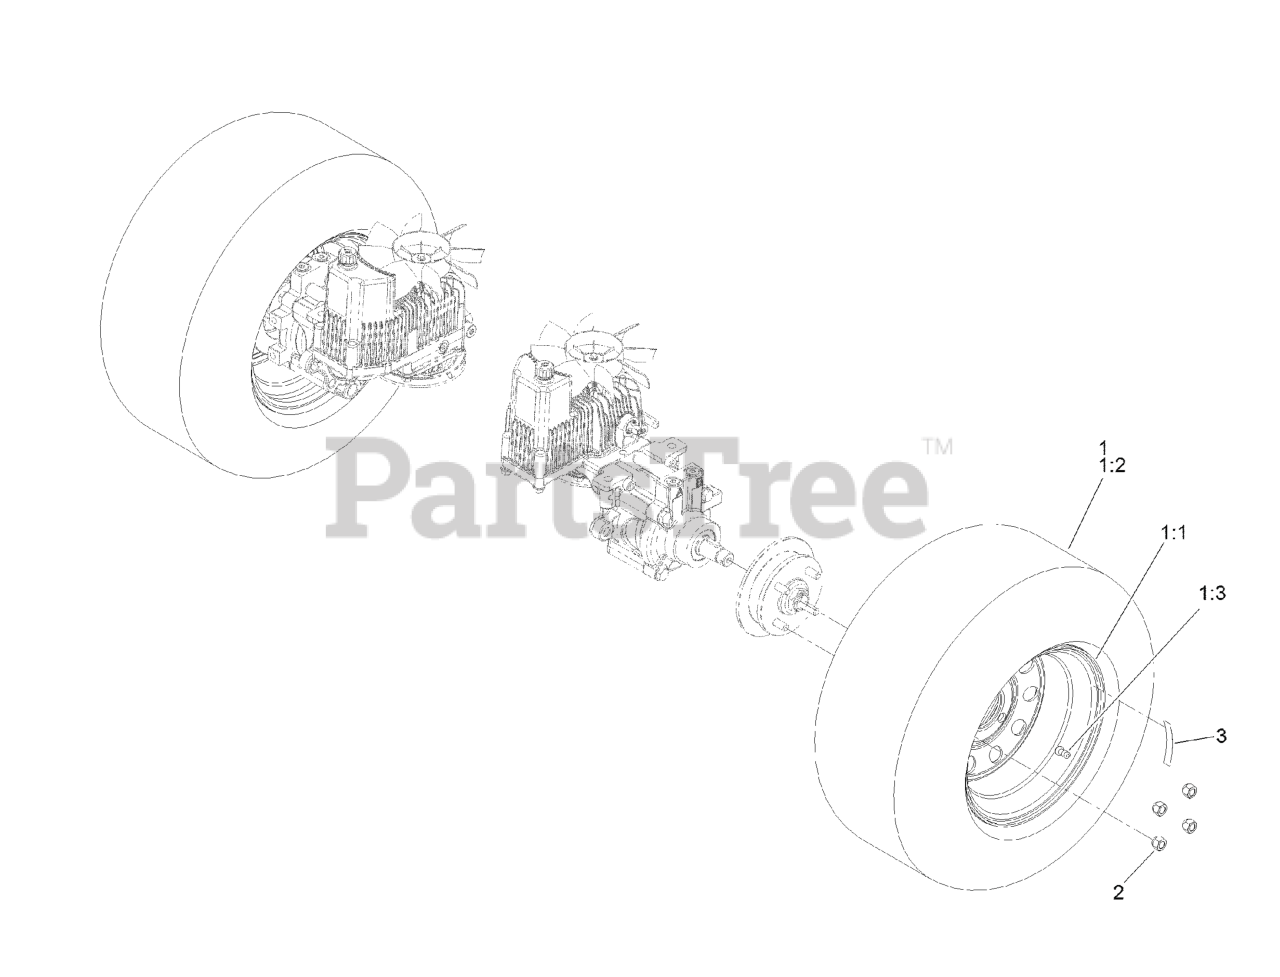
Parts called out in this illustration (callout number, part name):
1	WHEEL AND TIRE ASM
1:3	Stem-Valve
2	NUT-LUG
3	DECAL-TORQUE, WHEEL HUB LUG
